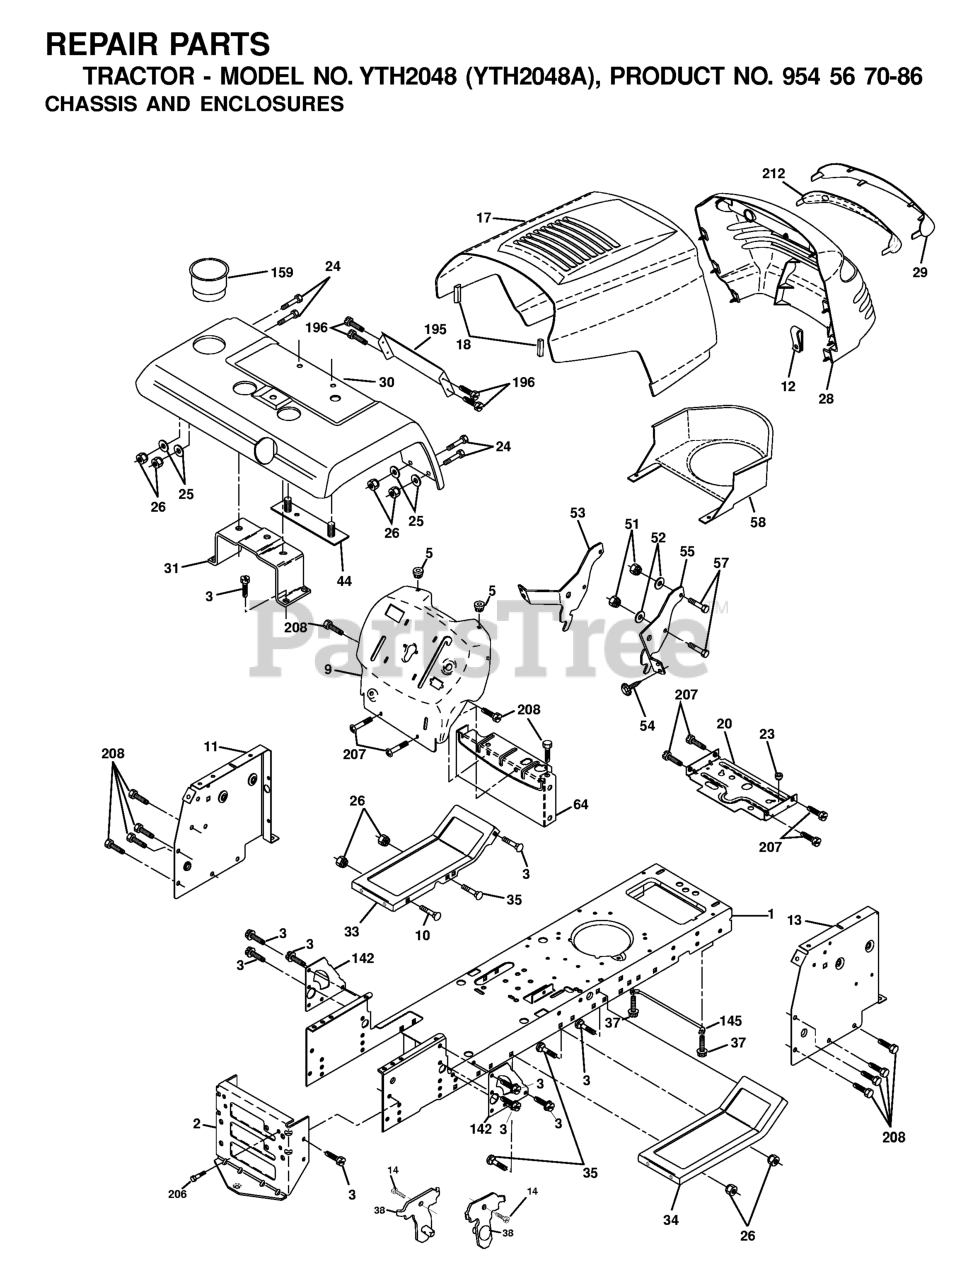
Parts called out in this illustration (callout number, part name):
1	CHASSIS STAMPING
2	DRAWBAR, 12GA
3	SCREW 3/8-16X3/4
5	BUMPER.RUBBER.HOOD
9	DASH SLKSCR
10	BOLT D
11	PANEL DASH LH
13	PANEL ASM, DASH RH
17	HOOD ASM.
18	BUMPER HOOD T
20	PLATE MTG
23	BUSHING.SNAP.NYL.BLK.
25	WASHER
26	NUT
28	GRILLE ASM
29	LENS
31	BRACKET ASM, FENDER
33	FOOT REST LH
34	FOOTREST RH
37	Screw 5/16-18 x 1/2 Hex, Self Tapping 5/16-18 x 1/2
38	BRACKET.ASM.PIVOT.MOWER.REAR
44	STRAP
51	LOCKNUT.NYLOC.1/4-20
53	BRACKET.GRILLE.LH
54	SCREW.HEX.WS.HD.8-18 X 7/8
57	BOLT
58	DUCT, INTAKE AIR
64	DASH LOWER
142	PLATE
145	ROD PIVOT CHASSIS/HOOD
196	SCREW CRT
206	SHOULDER BOLT 5/16-18TT
207	SCREW, 5/16-18 X 1/2
208	SCREW 3/8-16X1/2
212	REPL BY 532 1745-03
